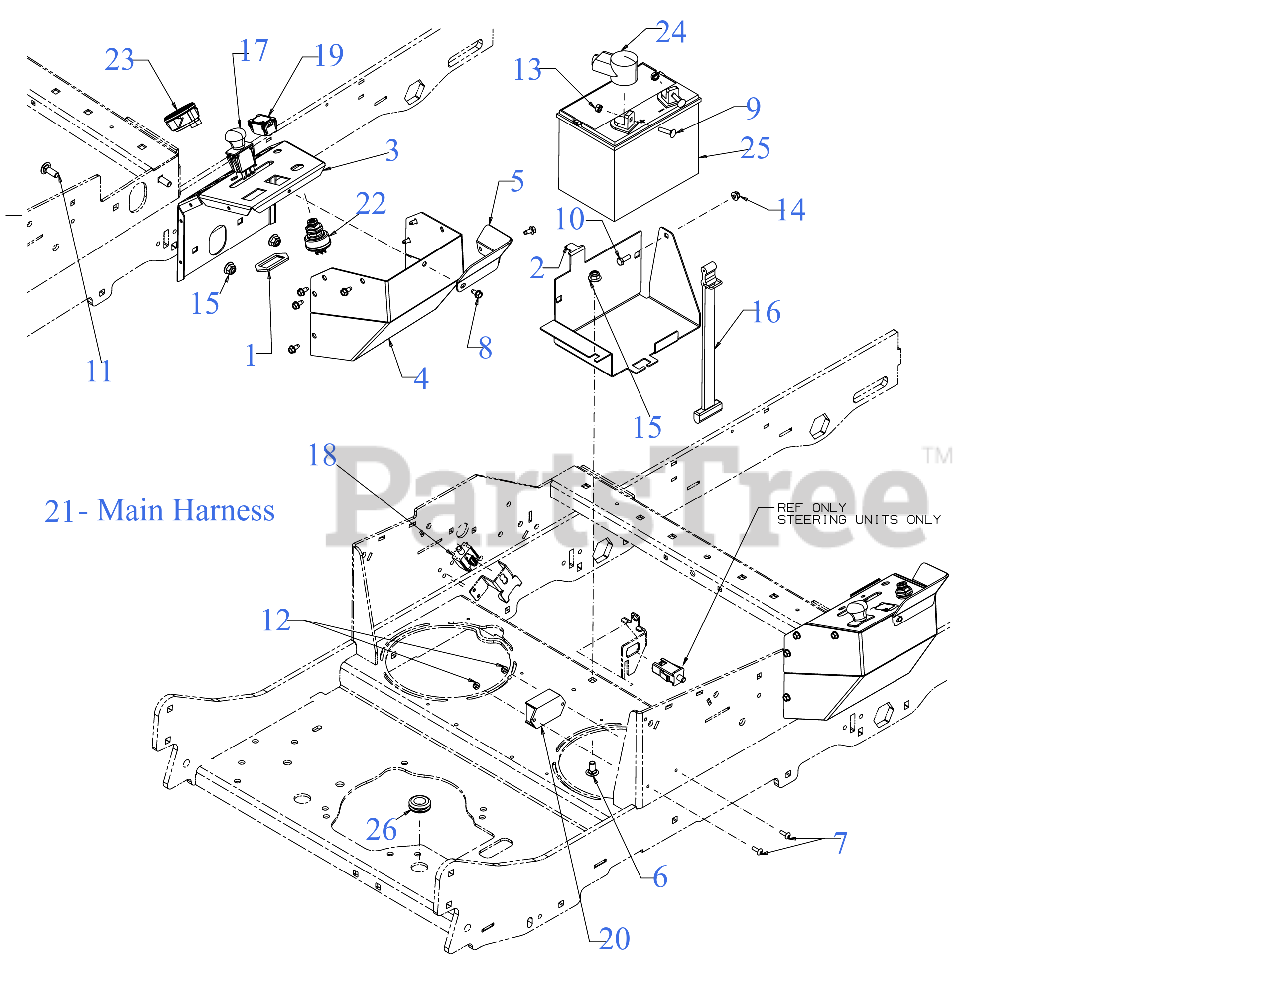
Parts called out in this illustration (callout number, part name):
1	BRACKET-PTO SWITCH
3	CONTROL POD (RH)
6	CARRIAGE BOLT 3/8-16 x .750 GR5
7	SCREW #10-24 x .62
8	SCREW 1/4-20 X.500
9	SCREW 1/4-20 x 1 GR5
10	SCREW 1/4-20X.75 GR5
11	CARRIAGE BOLT 3/8-16 x 1.00 GR5
13	SEMS NUT 1/4-20
14	FLANGE LOCK NUT
16	BATTERY RETAINER STRAP
17	PTO SWITCH (BLACK KNOB) TEXT SYM
18	3 POLE SWITCH ( NC-NO-NO)
20	CONTROL PANEL (SOFT CLUTCH)
21	WIRE HARNESS ASSEMBLY KOH/KAW EFI
22	KEY SWITCH (3 POSITION)
23	DUAL FUEL GAUGE
24	BATTERY BOOT
25	Purchase Battery Locally
26	RUBBER GROMMET
